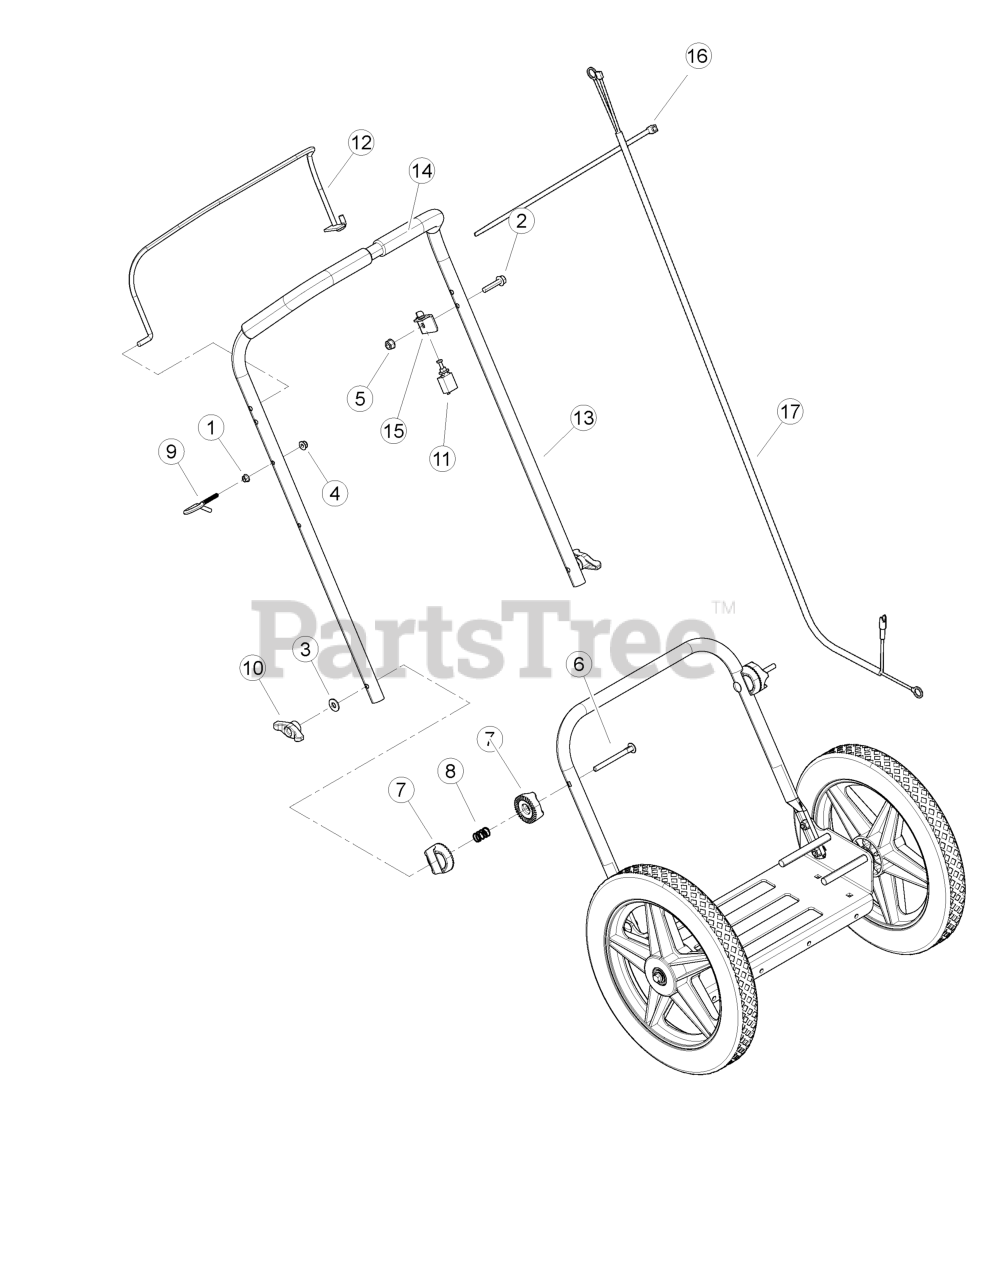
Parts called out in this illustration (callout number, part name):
1	NUT, 1/4"-20 SERRATED FLANGE NC ZP
2	BOLT, 5/16 × 1-1/2 FLANGE NC
3	WASHER, 5/16 FLAT
4	NUT, 1/4-20 NYLOCK-FLANGE
5	NUT, 5/16-18 NYLOCK FLANGE
6	BOLT, 5/16-18 × 3-1/2 LONG NECK GR5 CRG ZP
7	RETAINER, HANDLE BAR ADJUSTMENT
8	SPRING, RETAINER COMPRESSION
9	GUIDE, RECOIL ROPE
10	KNOB, 5/16-18 FEEM TEE
11	SWITCH, ENGINE KILL
12	ASSEMBLY, BAIL HW TRIMMERS
13	ASSEMBLY, UPPER HANDLE BAR WITH GRIPS
14	PAD, FOAM HANDLE BAR
15	BRACKET, HW KILL SWITCH
16	STRAP, 11 IN BLACK TIE
17	HARNESS, HONDA WT KILL SWITCH
